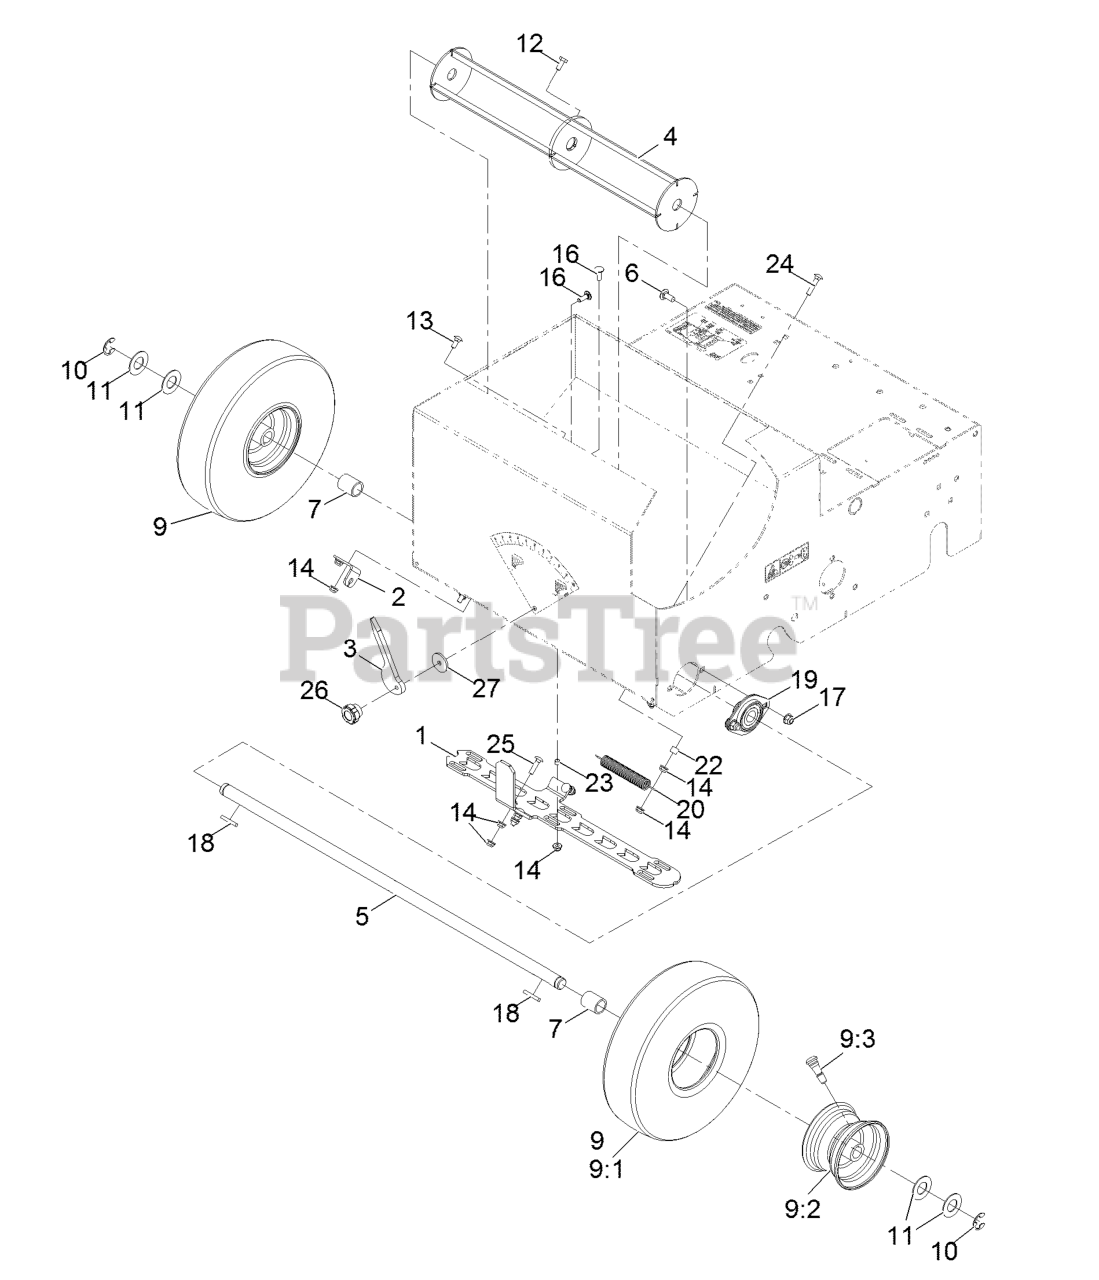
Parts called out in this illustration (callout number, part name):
1	GATE-SEED
2	BRACKET-FLOW, SEED
3	GAUGE-FLOW, SEED
5	AXLE-FRONT
6	SCREW-CARR
9	WHEEL ASM
9:2	WHEEL-RIM
9:3	VALVE
11	WASHER-FLAT
12	SCREW-HH
13	SCREW-CARR
16	BOLT-CARR
17	NUT-HF, NI
18	KEY-SQUARE
19	BEARING
20	SPRING-EXTENSION
24	SCREW-CARR
25	SCREW-PTH
26	KNOB-CHUTE
27	WASHER
